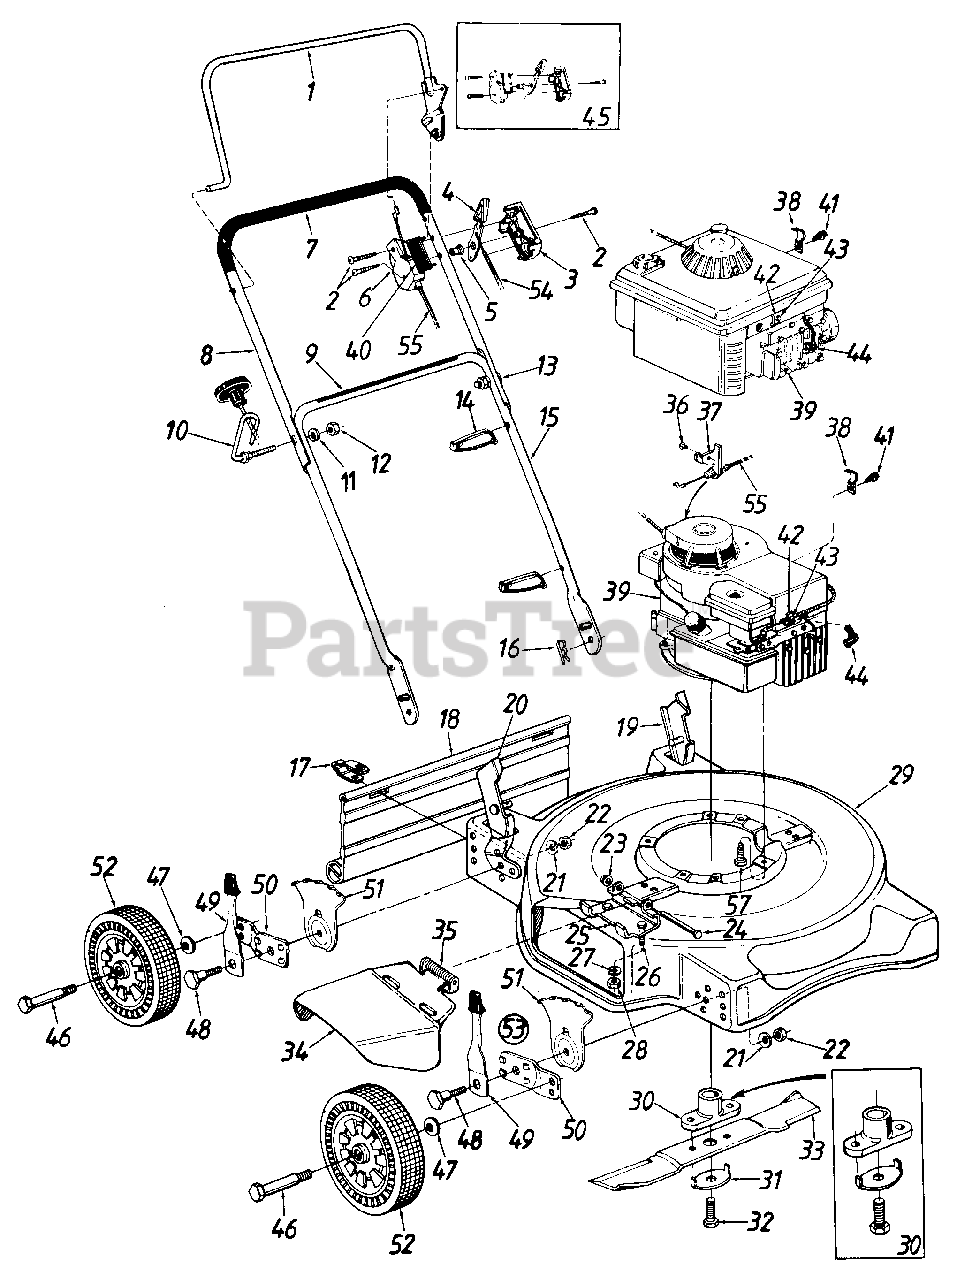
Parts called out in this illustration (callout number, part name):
1	HANDLE ASSY-CONTROL-LH
2	SCREW-TRUSS MACH
3	PANEL HALF-CONTROL
4	LEVER-THROTTLE CONT-REV
5	PIN-CONTROL DISC
6	PANEL HALF-CLUTCH
7	GRIP-SHRINK-25 IN
8	HANDLE-UPPER
10	SCREW-RECOIL HANDLE GUIDE
11	WASHER-LOCK-5/16
12	NUT-HEX 5/16-18
13	BOLT-CARRIAGE-CURV 5/16-18 X 1.38
14	TIE-CABLE
15	LOWER HANDLE
16	PIN-INTERN COT-5/16 DIA
17	CLIP-HINGE
18	FLAP-RR
19	BRACKET ASSY-HDLE-LH
20	BRACKET ASSY-HDLE-RH
21	WASHER-BELL .390 ID X 1.375 X .062
22	NUT-HEX 3/8-16
24	PIN-PIVOT
25	PLATE-ADAPTER
26	SCREW-HEX 1/4-20 X .50
27	LOCK WASHER 1/4 DIA
28	NUT-HEX 1/4-20
31	KIT-BLADE MOUNTING
32	SCREW-HEX 3/8-24 X 1.50 GR.5
33	BLADE-20IN
34	DEFLECTOR ASSY-CHUTE
35	SPRING-TORSION
37	BRACKET-CABLE
38	CLAMP-CASING
41	SCREW-HEX B-TAP #10 X .38
42	CLAMP-CONDUIT
43	SCREW-HEX WASH HD AB-TAPP #8 X .38
44	INSULATOR-SPARK PLUG
45	KIT-THROTTLE CONTROL
46	SCREW-SHLD .498 DIA X 1.450
47	WASHER-BELL .400 ID X .88 X .060
48	SCREW-SHLD
49	LEVER & KNOB ASSY
50	BAR-PIVOT
51	PLATE-HGT ADJ
52	WHEEL ASSY W/TIRE
53	ADJUSTER ASSY-HGT-RH
54	WIRE-THROTTLE-52 IN
55	WIRE-THROTTLE
57	SCREW-HEX
17036-0483	DECK ASSEMBLY-20INCHARCOAL - CHARCOAL GRAY (0483)
17036-0498	DECK ASSEMBLY-20IN(CUB YELLOW) - OLD CUB YELLOW (0498)
17036-0629	DECK ASSEMBLY-20INSILVER FLAK - SILVER FLAKE (0629)
17036-0638	DECK ASSEMBLY-20IN - MTD/TROY-BILT RED (0638)
17036-0662	DECK ASSEMBLY-20IN(OYSTER GRAY) - OYSTER GRAY (0662)
